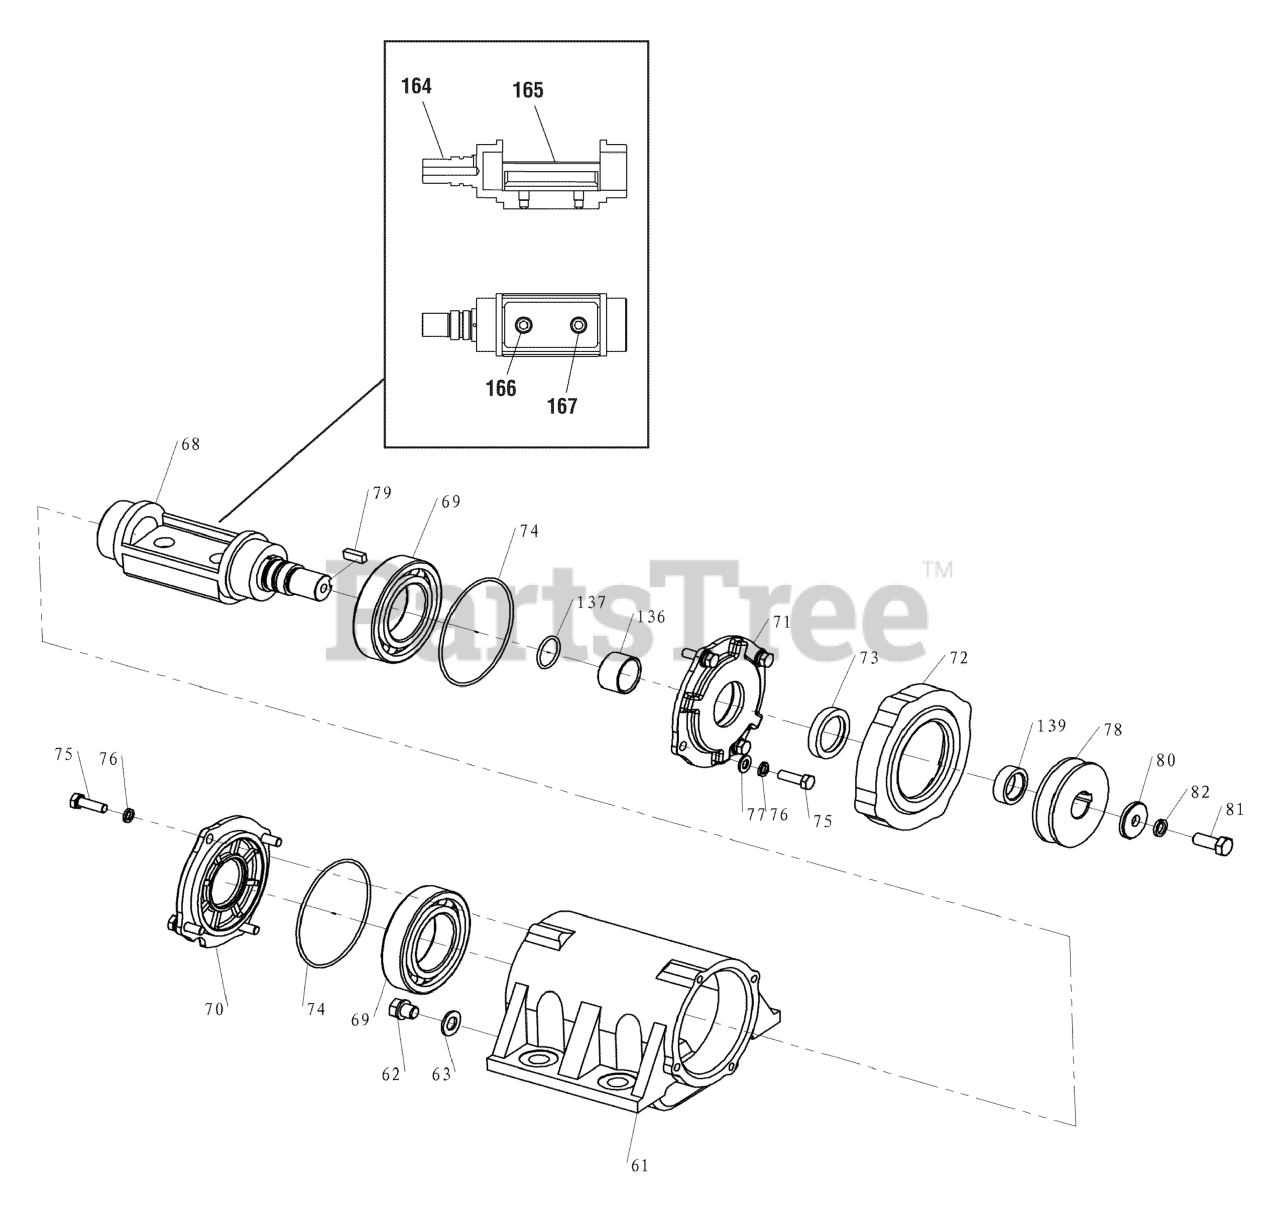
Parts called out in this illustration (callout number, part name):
61	VIBRATING CASE
62	PLUG SCREW
63	PACKING PIECE
68	ECCENTRIC ROTATOR ASSEMBLY
69	BEARING 6211-GB276
70	CASE COVER, RH
71	CASE COVER, LH
72	PROTECTIVE COVER
73	OIL SEAL 35×8, GB9877
74	O-RING, 97.5 x 3.55, GB3452.1
75	BOLT, M8 x 20, GB5783
76	WASHER, Spring, 8, GB93
77	WASHER, 8, GB95
78	PULLEY
79	KEY, C8, GB1096
80	PULLEY WASHER
81	BOLT, M10 × 25, GB5783
82	WASHER, Spring, 10, GB93
136	BEARING
137	O-RING, 25.8 x 2.65
139	SHAFT BUSHING
164	SHAFT, MS90
165	BOB WEIGHT, MS90
166	SCREW, Hex Socket
167	WASHER, Spring, 10, GB93
